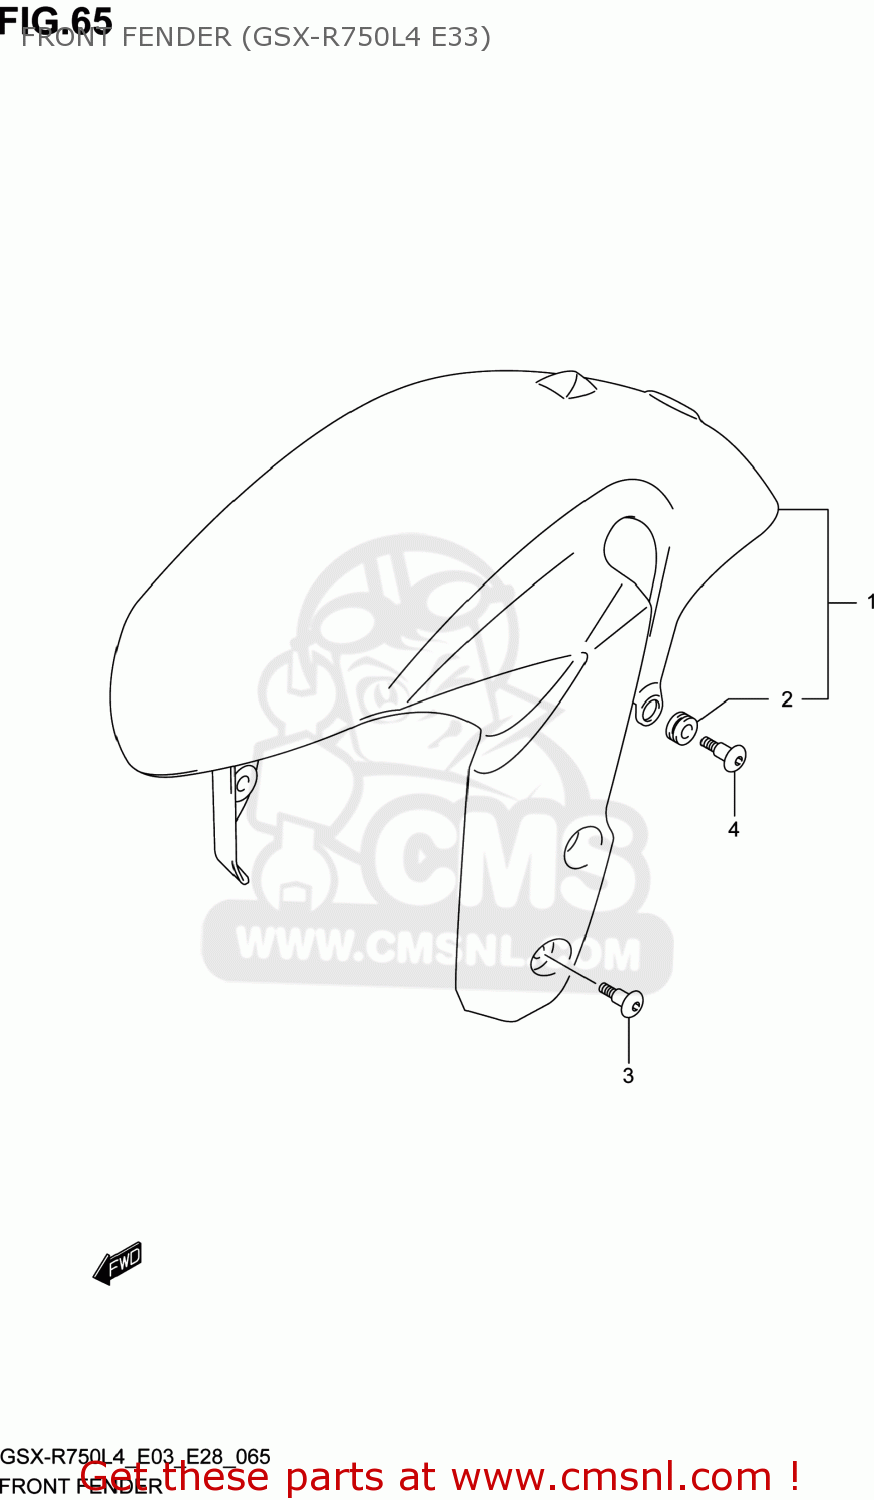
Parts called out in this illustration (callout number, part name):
1	FENDER ASSY,FR(WHITE)
2	CUSHION
3	SCREW(6X16)
4	SCREW(6X16)
